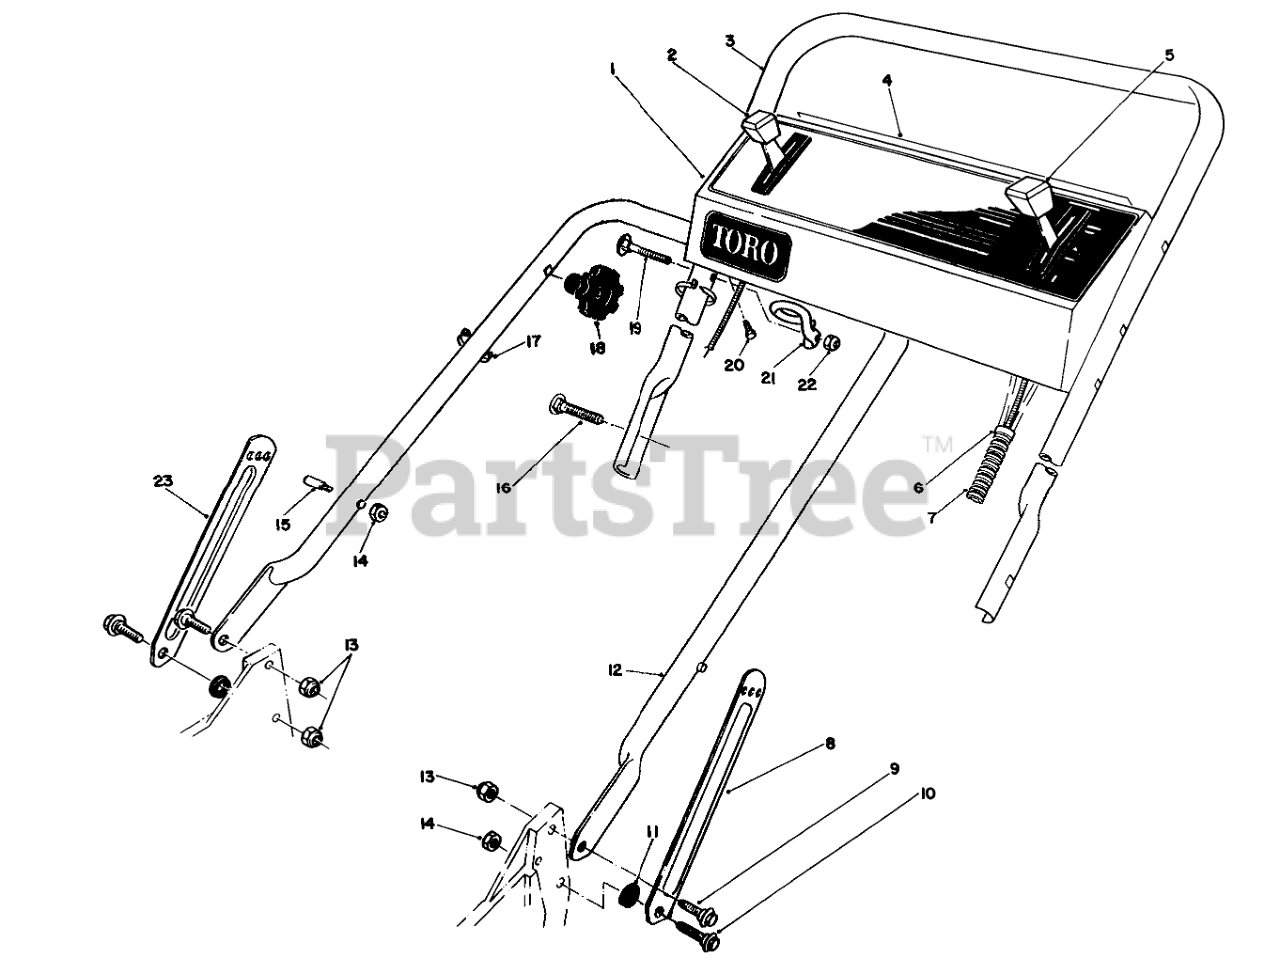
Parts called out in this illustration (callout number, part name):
1	Panel-Control
2	Control-Ground Speed
3	UPPER HANDLE
4	DECAL-PANEL, DANGER
5	THROTTLE CONTROL
6	FITTING-RING
7	CONTROL CABLE COVER
8	LH HANDLE LATCH
9	SCREW-SHOULDER
10	SCREW-SHOULDER
11	SPACER
12	LOWER HANDLE ASM
13	NUT-LOCK, NI
14	NUT-LOCK, NI
15	HANDLE PIN
16	5/16-18 X 2 HNDLE SCREW
17	TIE-CABLE
19	HANDLE SCREW
20	SCREW-HWHTF
21	Guide
22	NUT-LOCK, NI
23	RH HANDLE LATCH
